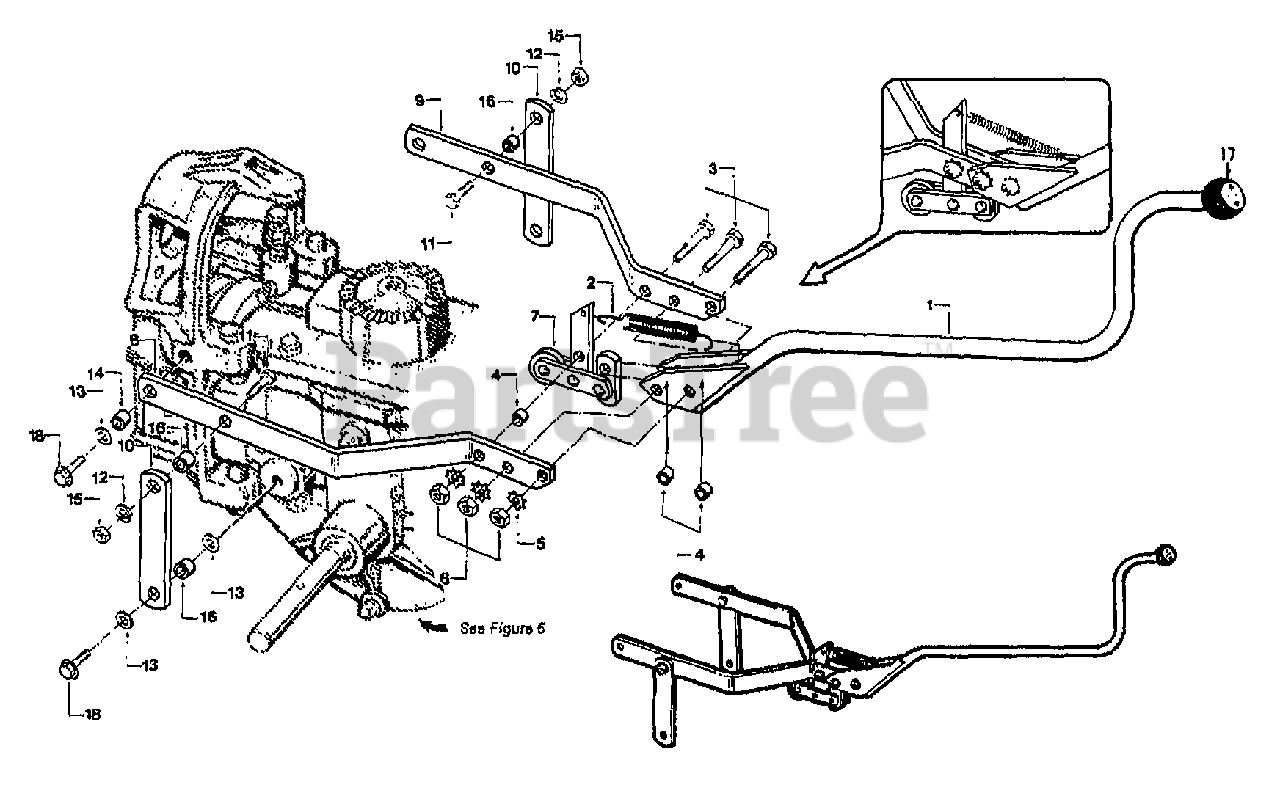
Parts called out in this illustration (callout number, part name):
1	ASSM-FOR/REV LEVER OPC
2	SPRING-.436 X 3.25
3	SCR-HH 5/16-18X1.5 G5 ZP
4	BUSHING-.5X.316X.375 PM
5	WASHER-LK .312 EXT TOOTH
6	NUT-HEX 5/16-18 ZP
7	ASSM-ROLLER BLACK
8	YOKE-LH BLACK
9	YOKE-RH BLACK
10	BAR-CLUTCH YOKE BLACK
11	SCR-HH 3/8-16X1.0 G5 ZP
12	WASHER-LK .375 @ DEPL
13	WASHER-FLAT 3/8 SAE
14	BUSHING-.5X.375X.325
15	NUT-HEX 3/8-16 ZP
16	BUSHING-.5X.375X.3
17	KNOB - PLASTIC KNOB N/A SEPARATELY DUE TO SPECIAL PROCEDURE IN ATTACHING KNOB.
18	SCR-HFLK 3/8-16X1.00 ZP
